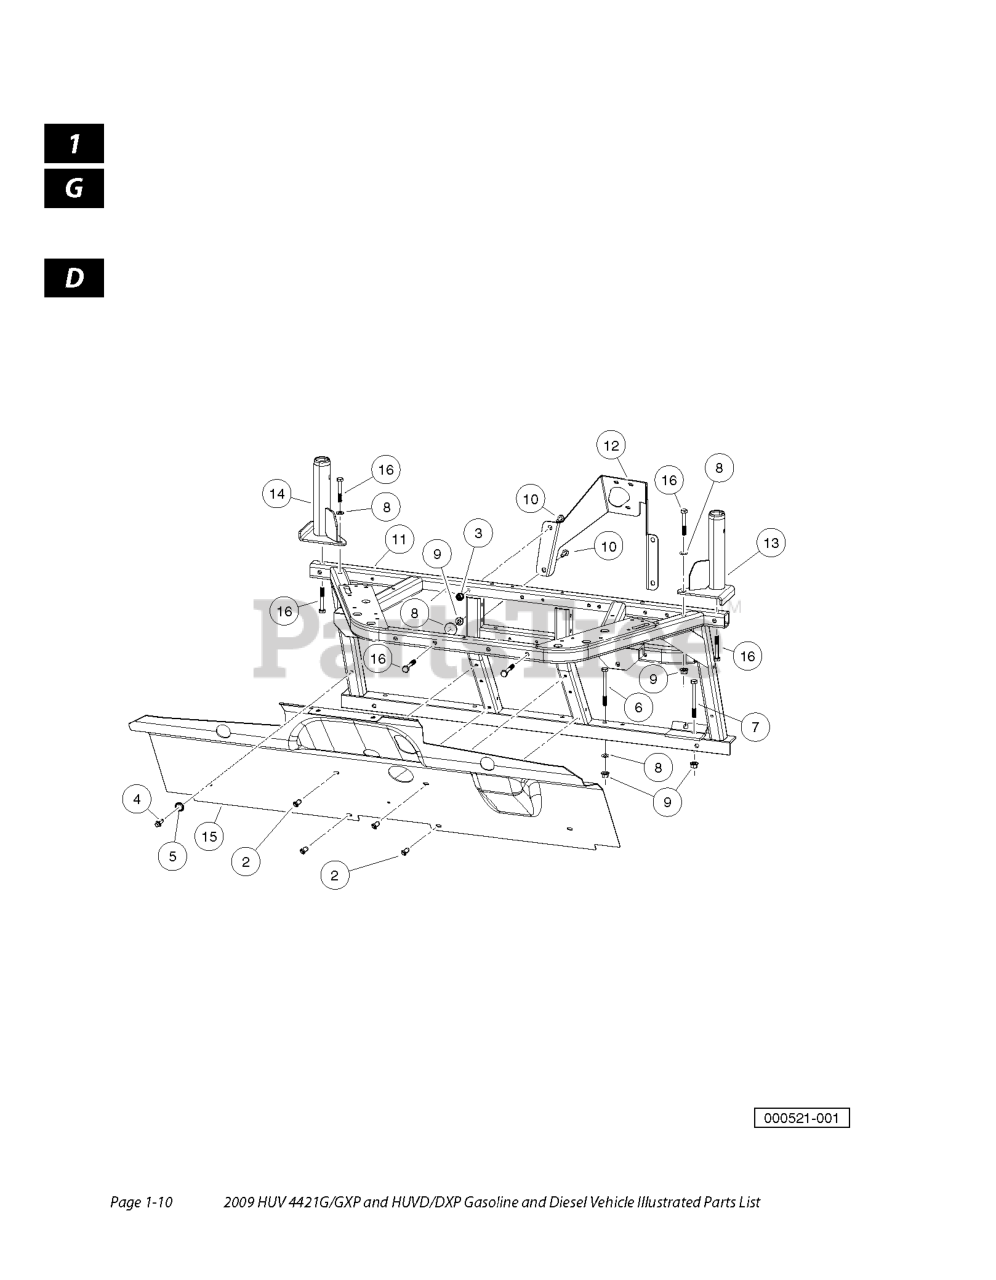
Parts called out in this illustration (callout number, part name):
2	BLIND RIVET, PUSH TYPE
3	NUT, M8, ALL METAL LOCK
4	M8-1.25X20 TAPTITE
5	WASHER, FLAT, 3/8, BLK FIN
6	BOLT,M10X1.50X100 BLACK
7	BOLT, M10 X 1.50 X 110 BLACK
8	WASHER HARD, M10
9	NUT FLG M10 X 1.5 MECH DEF
10	BOLT FLG, M8X1.25X65
11	WELDMENT, DASH, FRONT
12	BKT, COLUMN, STEERING
13	WELDMENT, FRT, BASE, ROPS, RH
14	WELDMENT, FRT, BASE, ROPS, LH
15	GUARD, SPLASH, GAS INJECTION
16	BOLT, M10 X 1.50 X 65
